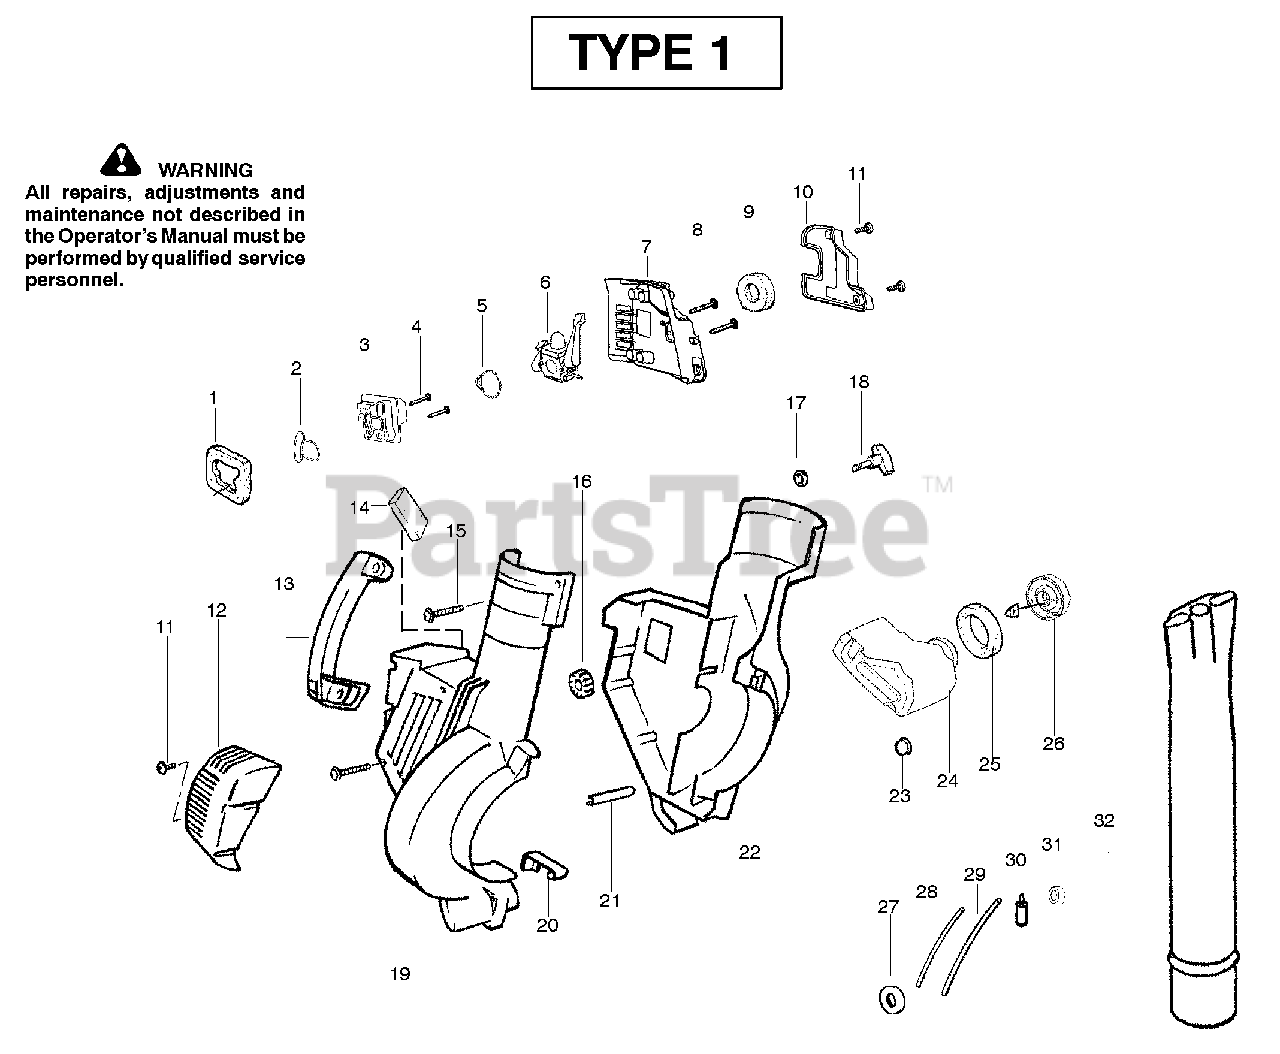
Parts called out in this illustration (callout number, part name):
1	Air Dam (kit)
2	Gasket-Adapter (kit)
3	Carburetor Adaptor
5	Gasket-Carburetor (kit)
6	Kit-Carb Ass'y. Zama-(C1Q-W11C)
6	Kit-Carb Ass'y. Walbro-(WT-606)
8	Screw-Carb.
9	Filter-Air
10	Cover-Air Filter
12	Guard-Muffler
14	Foam - 71.12mm (kit)
16	Isolator
18	Knob-Blower
19	Housing-Right
20	Spring-Cover Latch
21	Guide-Starter Rope
22	Housing-Left
23	Isolator-Crankcase
24	Assy-Fuel Tank
25	Gasket-Fuel Tank
26	Fuel Cap w/Retainer
27	Grommet-Shroud
28	Kit-Line Carb/Purge
29	Kit-Line Tank/Purge
30	Assy-Fuel Pick-up
31	Grommet-Fuel line (kit)
32	Tube-Blower
